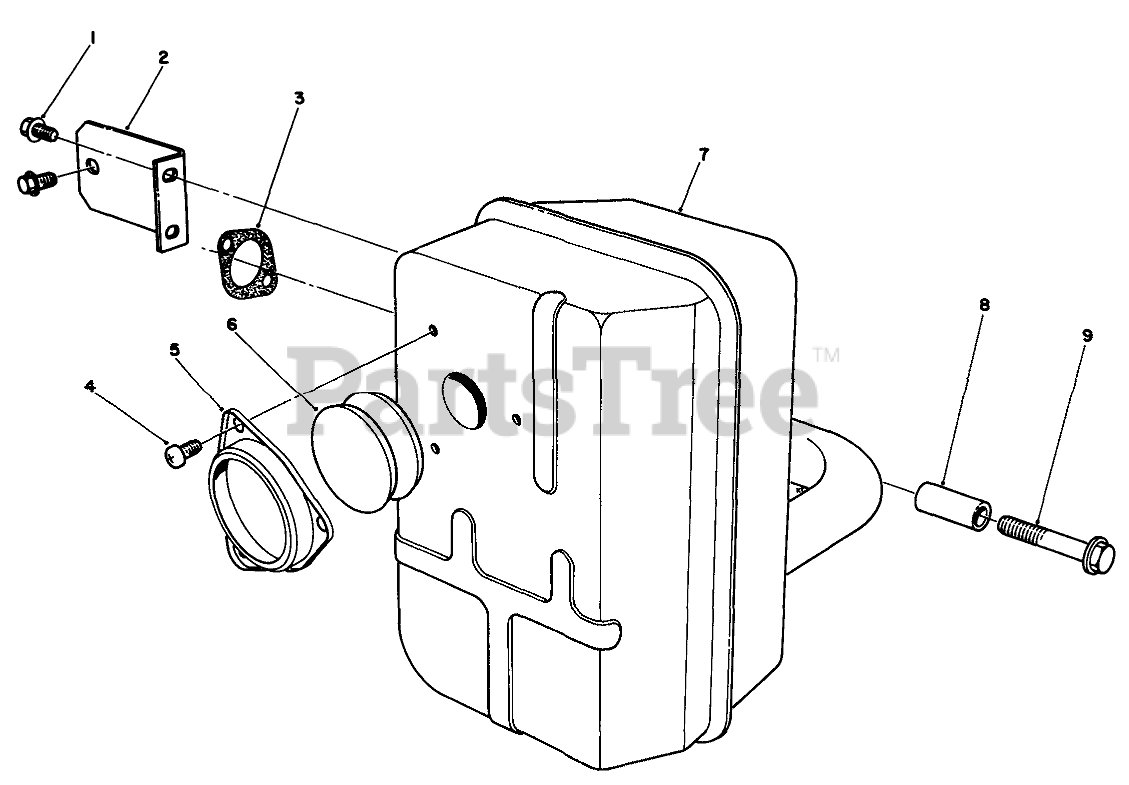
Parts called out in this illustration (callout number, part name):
1	Bolt-Flanged (8X12)
5	Cap
6	Arrester-Spark
7	Muffler Assembly (Incl. Ref. #4, 5, & 6)
9	Bolt-Flanged (8X45)
